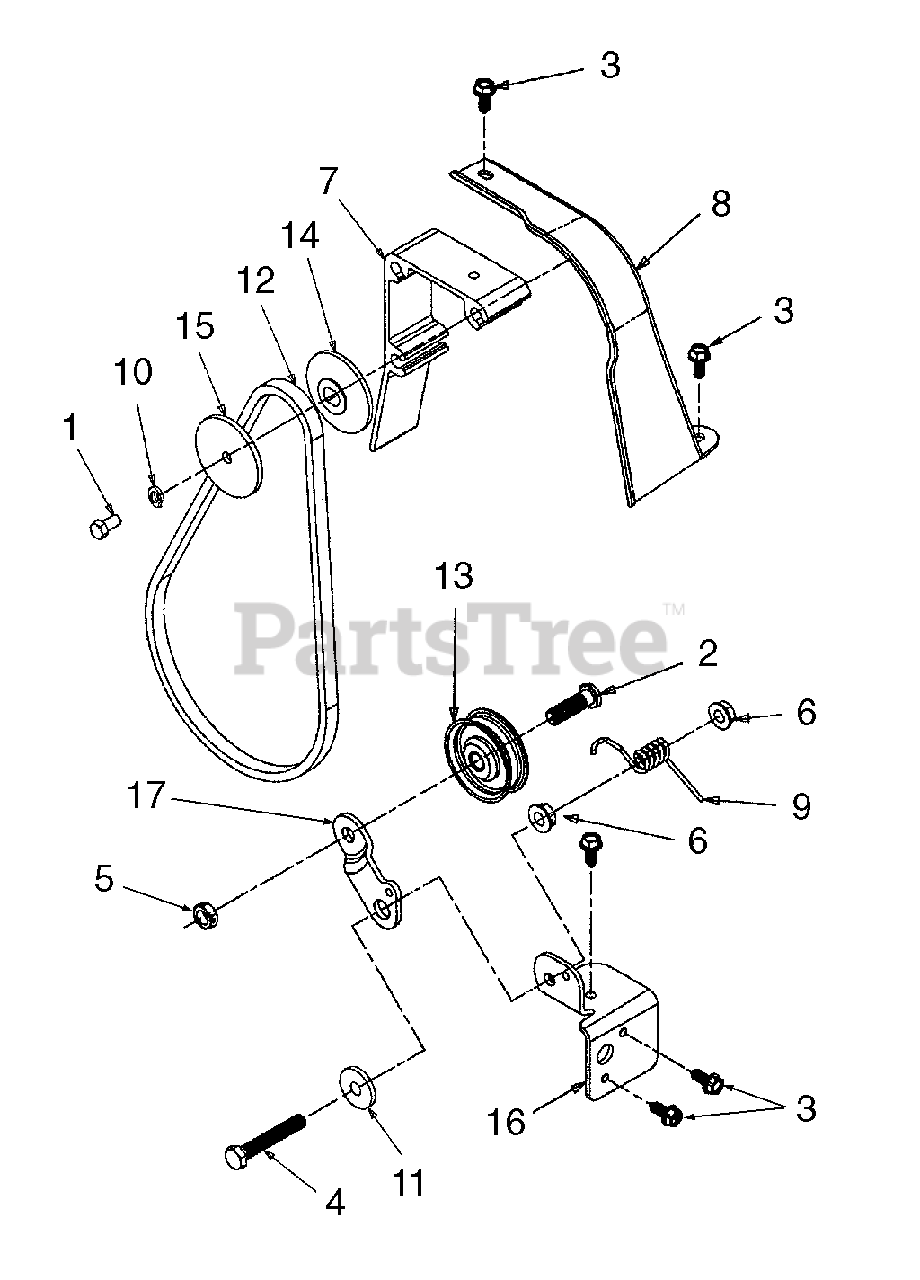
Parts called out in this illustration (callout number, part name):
1	Screw, Hex Cap, 1/4-28 x .50
2	Screw, Hex Cap, 3/8-16 x 1.25
3	Screw, Hex Wash Hd Tapp. 1/4-14 x .625
4	Screw, Hex Cap, 5/16-18 x 2.0
5	Nut, Hex Cent-L Jam, 3/8-16
6	Nut, Hex Flange Lock, 5/16-18
7	Adapter, Engine Mtg
10	Washer, Lock, 1/4
11	Shoulder Spacer, .50 ID x .27 Lg
12	V-Belt, 3/8 x 29.0 Lg
13	Pulley, Flat Idler
14	Pulley Half, 2.0 Dia
15	Pulley Half, 2.0 Dia
16	Bracket, Idler Pivot
17	Bracket, Idler
